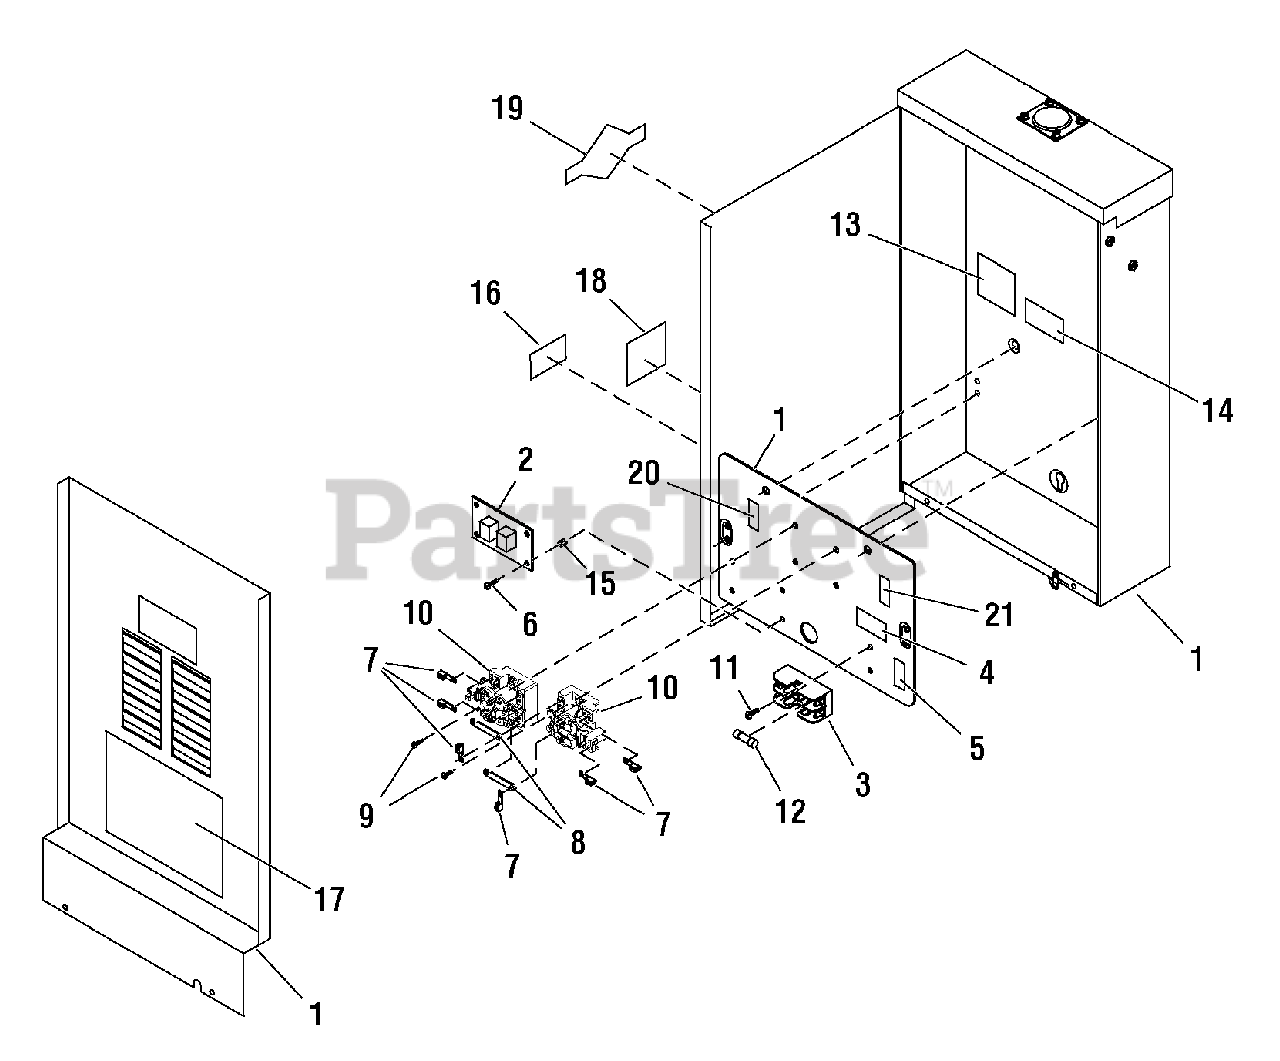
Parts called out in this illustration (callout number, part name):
1	LOADCENTER
5	DECAL
7	TERMINAL
